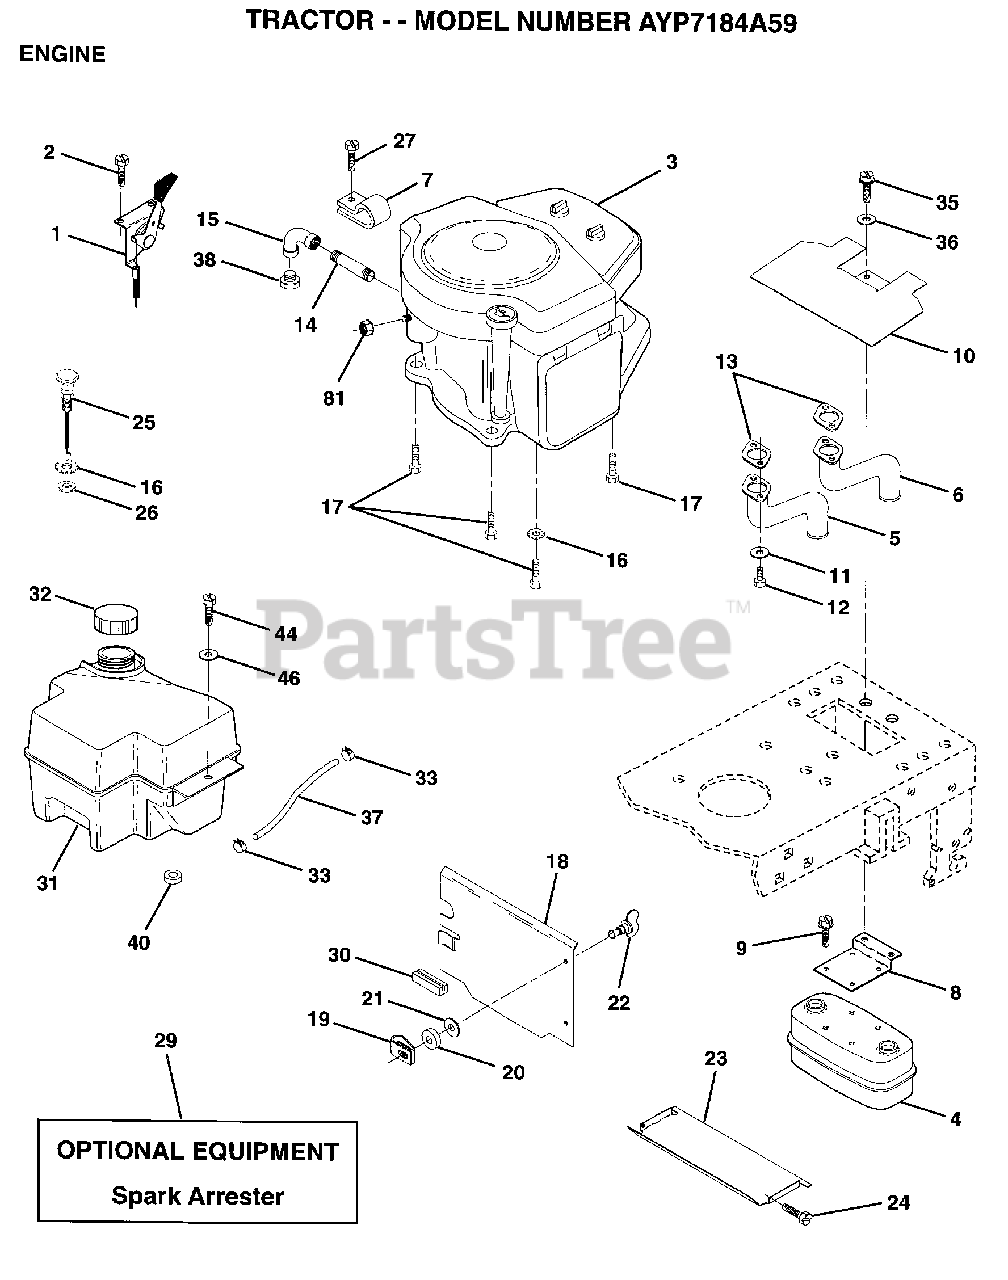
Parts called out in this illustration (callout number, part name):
1	CONTROL.THR.33.
2	SCREW LT
5	EXHAUST.B&S.18.LH
6	EXHAUST.B&S.18.RH
7	CLAMP.TUBE.DBL.EN
8	BRACKET MUFFLER
9	SCREW ST
10	SHIELD.HEAT.
11	LOCKWASHER
14	PIPE NIPPLE LT
15	ELBOW
16	LOCKWASHER
17	SCREW LT
18	SHIELD HEAT
19	RECEPTACLE LT
20	RETAINER LT
21	WASHER
22	STUD.1/4.TURN
24	SCREW
25	CONTROL CHOKE
27	SCREW.10-24X1/2
32	CAP ASM FUEL
33	HOSE CLAMP
35	SCREW
36	WASHER
37	LINE FUEL
44	SCREW HEX CRT
46	WASHER
81	NUT
